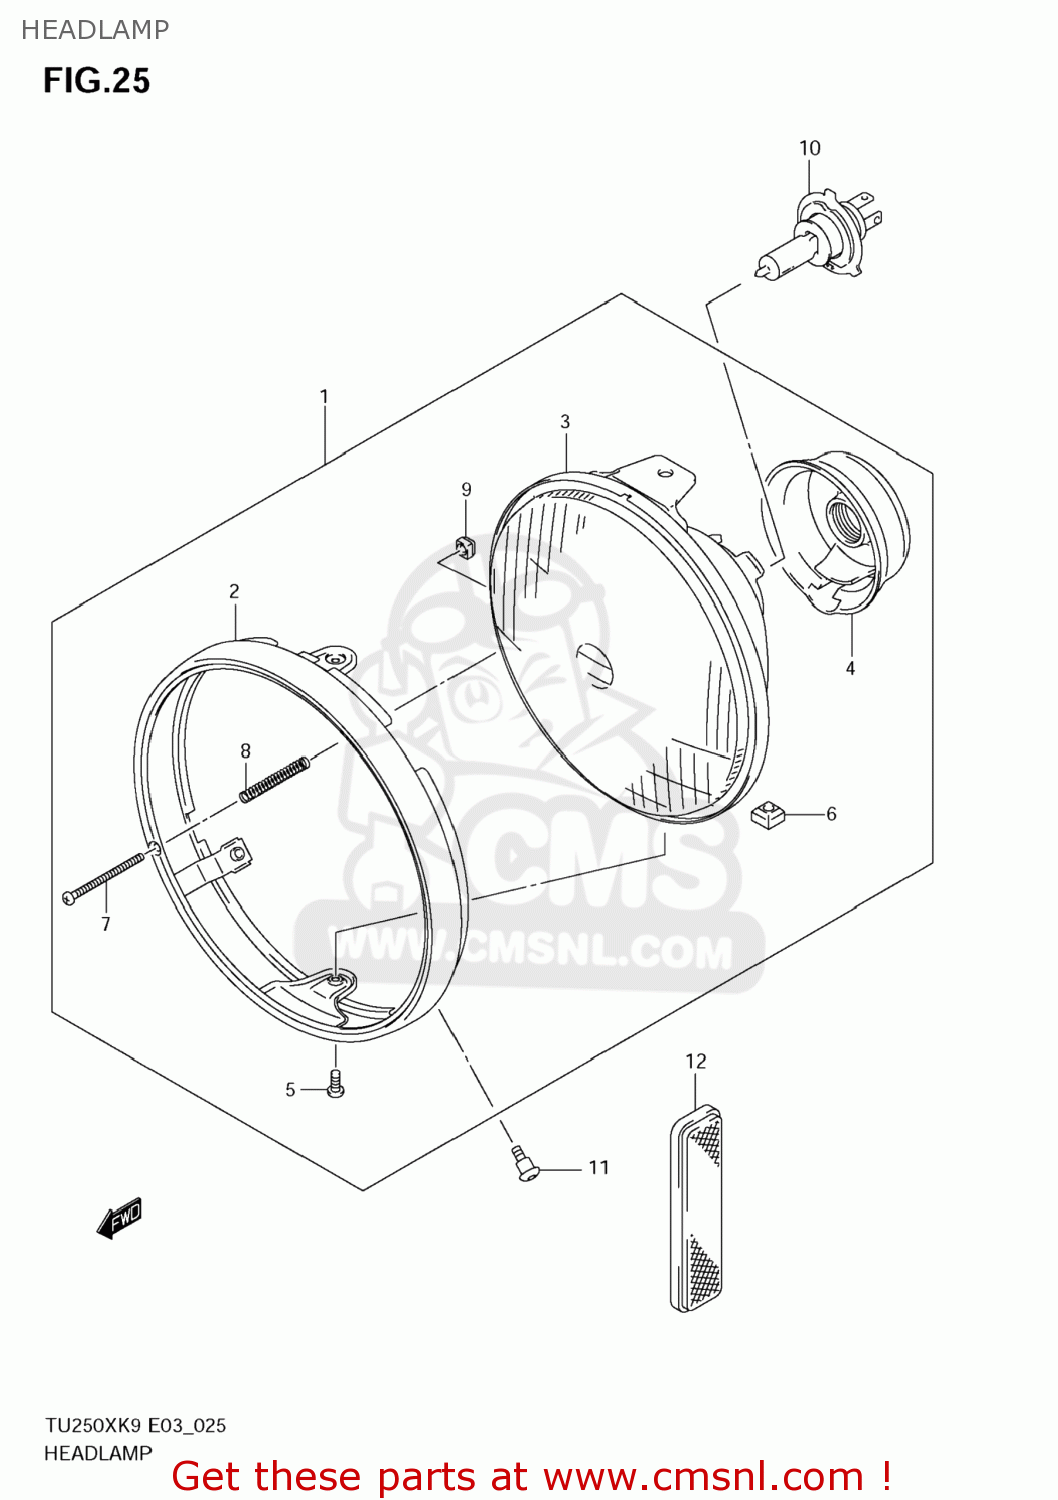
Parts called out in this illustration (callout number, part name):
1	HEADLAMP ASSY
2	RIM
3	UNIT,LAMP
4	COVER,SOCKET
5	SCREW
6	NUT
7	SCREW,ADJUSTING(4X45)
8	SPRING,HEAD LAMP ADJUSTER
9	NUT,HEADLAMP ADJUST
10	BULB(12V60/55W,H4)
11	SCREW(5X12)
12	REFLEX REFLECTOR ASSY,FR SIDE
